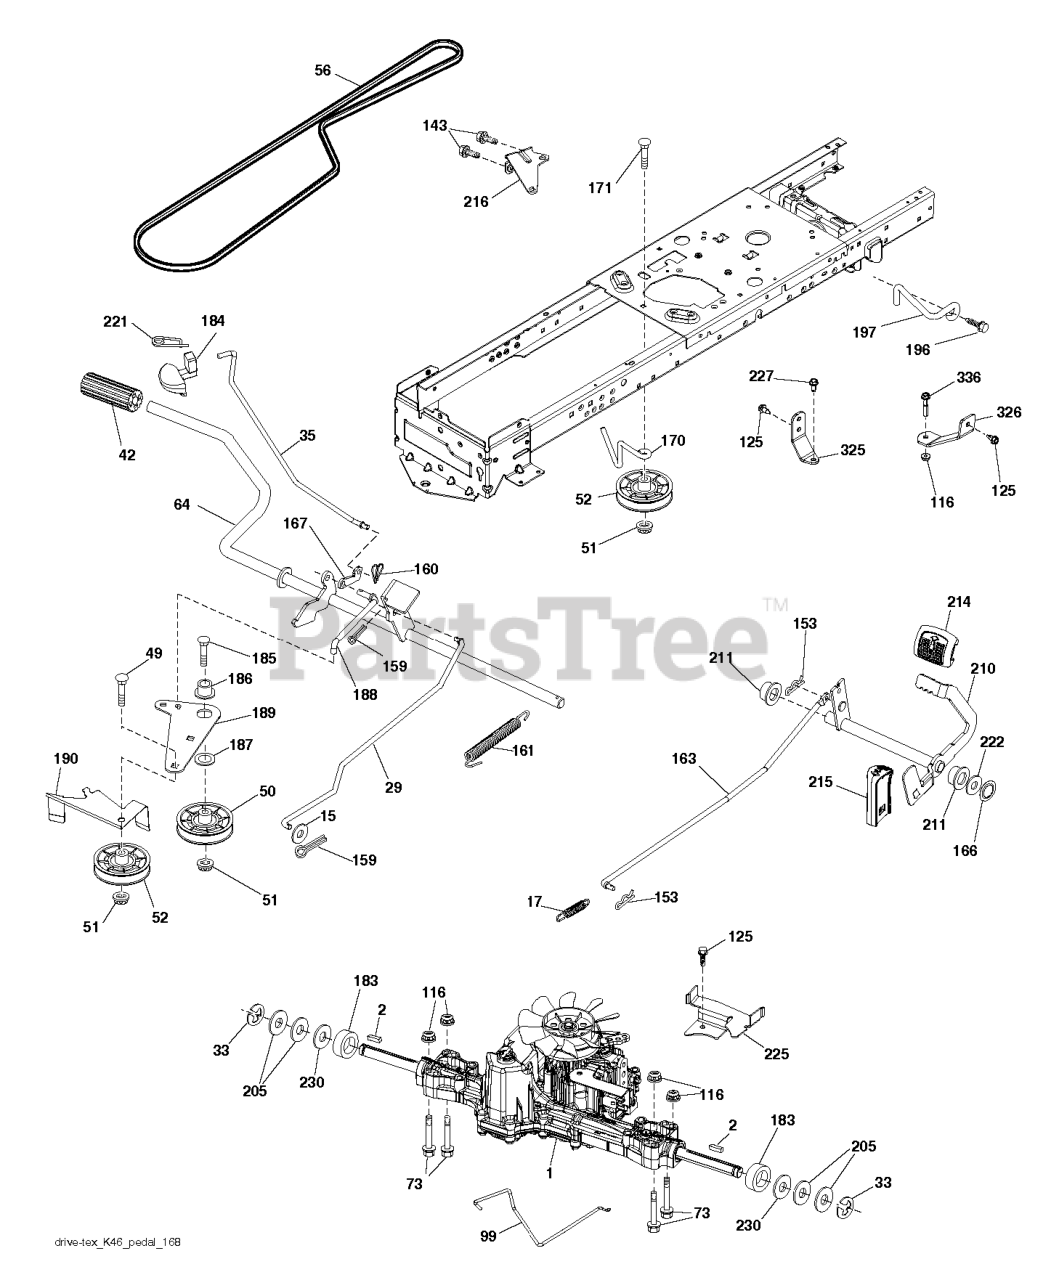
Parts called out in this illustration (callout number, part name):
2	SQUARE KEY
15	WASHER
17	SPRING.BRAKE.K46.GREEN
29	ROD.BRAKE.K46
35	ROD .BRAKE. PARKING. GT. HUSQ.
42	PEDAL COVER T
50	IDLER.FLAT.910.OFFSET
51	NUT LOCK FLG 3/8-16 UNC
52	IDLER.V-GROOVE.910.OFFSET
56	V-BELT.MOWER.92.40.42/K46
64	SHAFT.ASM.PEDAL.BRK.CNTR
73	BOLT
99	ROD.SPRING.BYPASS.K46.LT.Z
116	NUT LOCK HEX FLANGE 5/16-18
125	SCREW
143	SCREW LT
153	RETAINER M
159	COTTER PIN
160	RETAINER CLIP
161	SPRING, RETURN LT
163	ROD.CONTROL.K57R.K46
166	NUT.PUSH.625
167	LATCH.BRAKE.SPRING
170	KEEPER.V-IDLER.CENTER.
171	BOLT
183	SPACER AXLE
184	HANDLE.PARKING.BRAKE.H (BLK)
186	SPACER.RETAINER
187	WASHER 12/32X2X10GA
188	RP.LINK.CLUTCH.GROUND.DRIVE
189	BELLCRANK.GROUND.DRIVE.TEX.
190	KEEPER.BELLCRANK.DRIVE
196	SCREW 3/8-16X1
197	CLUTCH.ANTIROTATION.WIREFORM.
210	ROCKER.ASM.PEDAL.CONTR
211	BEARING.NYLON
214	PEDAL.FORWARD.PAD.TEX
215	PEDAL.COVER.REVERSE.CRD.X498GY
216	BRACKET.PULLEY.IDLER.W/TEX
221	RETAINER.SPRING.CLIP.H
222	WASHER 21/32 X 1-1/4 X 10 GA.
225	KEEPER.BELT.TRANSAXLE.K46
227	SCREW.THDROL.5/16-18X3/4.TTY
230	WASHER.HARDENED
325	BRACKET.TRQ.STP.46.20".TIRE.LH
326	BRCKT.PNT.TRQ.STP.46.20TIRE.RH
336	BOLT.5/16-18X1-3/4.FLANGED.HEX
